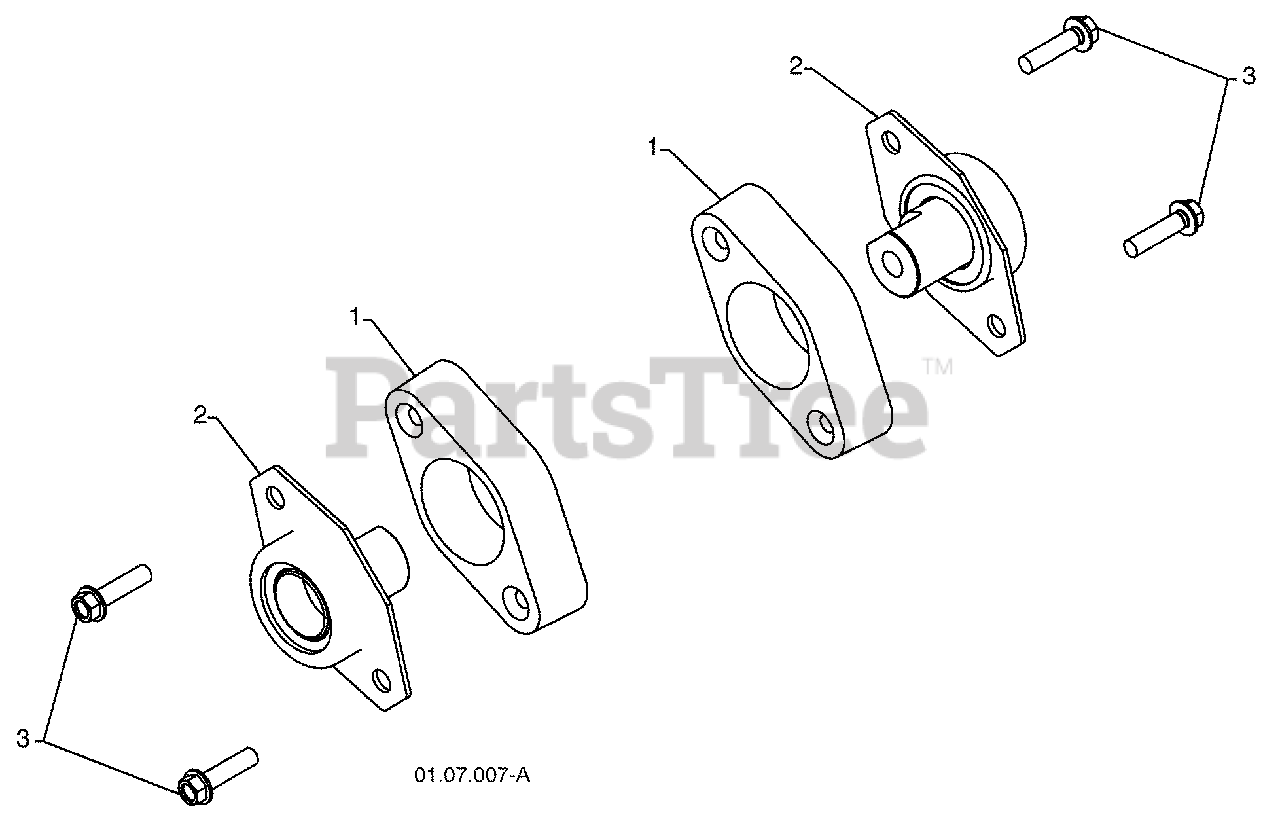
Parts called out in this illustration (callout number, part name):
1	PLASTIC RETAINER
2	AUGER BALL BEARING
3	SCREW 5/16-18 X 1.00
